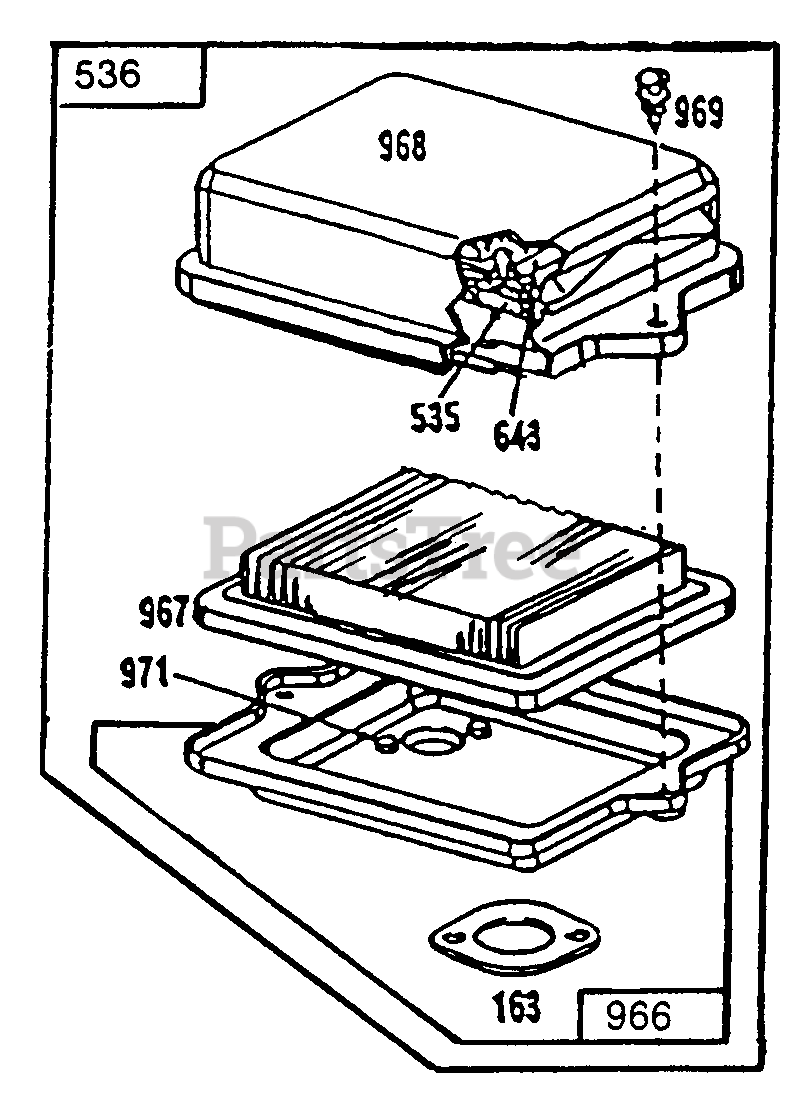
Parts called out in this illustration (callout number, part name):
163	Gasket--Air Cleaner
535	Element--Air Cleaner
536	Cleaner--Air Ass'y.
643	Retainer--Air Cleaner
966	Base--Air Cleaner
967	Filter--Air
968	Cover--Air Cleaner
969	Screw--Cover Mtg.
971	Screw--Air Cleaner
